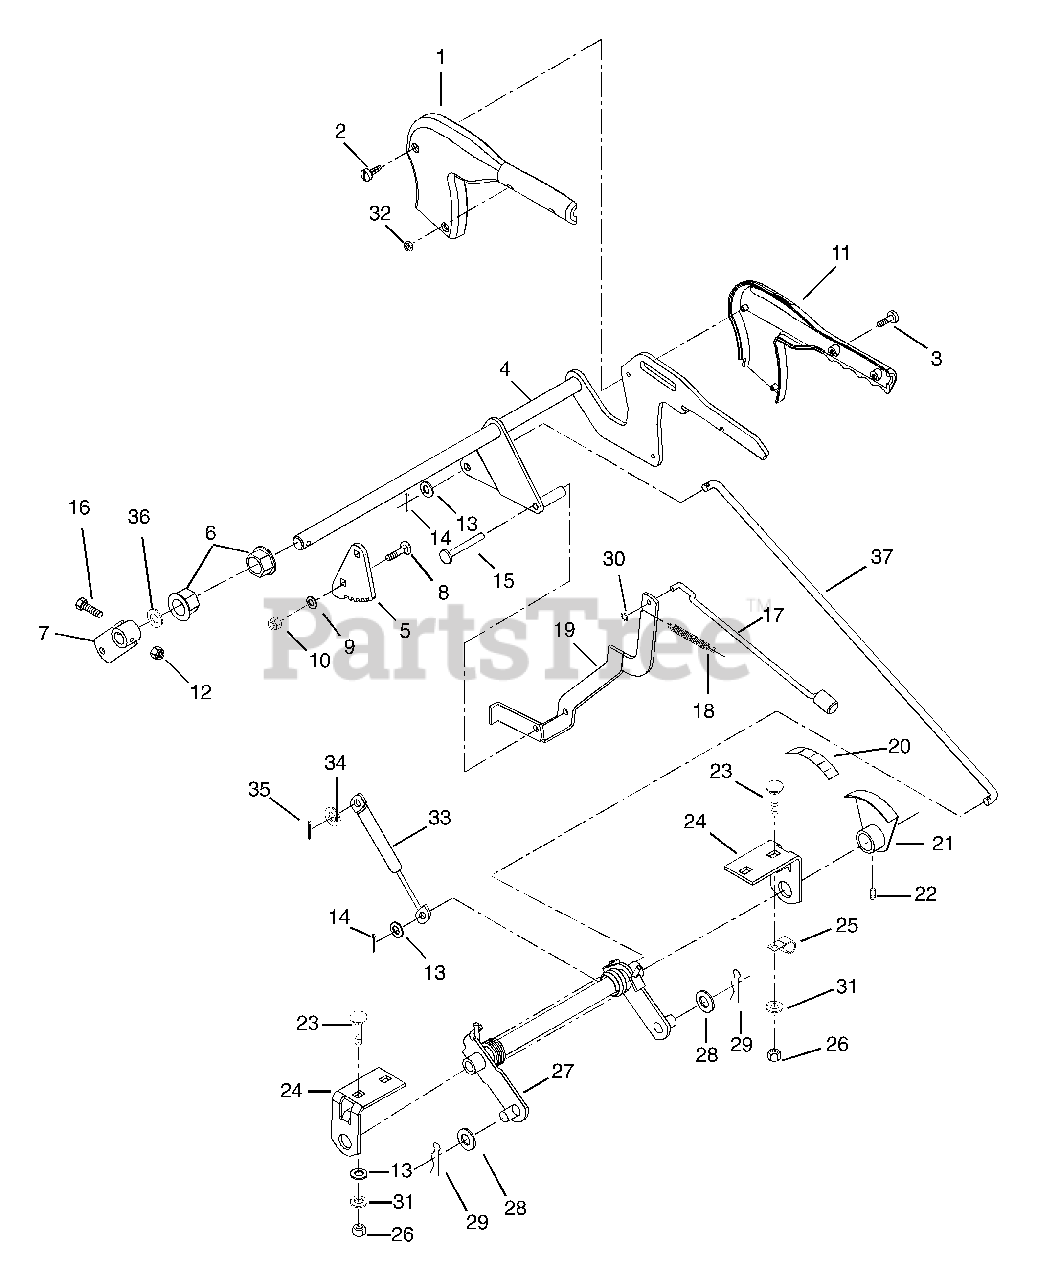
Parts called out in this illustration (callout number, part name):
1	COVER - LIFT RH
2	SCR-TAP 10-16X1.125HI-LOTPHBL
3	SCR-MCH 10-24X.62 P/HD
4	LEVER, LIFT
5	QUADRANT, LIFT
6	BSHG-FLG .750X.873HEXX.53X1.18
7	ARM, LIFT
8	@BLT-RDHDSQNK .31-18X.75 G5YZ
9	WSHR-FL-STL .323X.625X.062 YWZ
10	@NUT-LK-CTR .31-18 YWZC
11	COVER - LIFT LH
12	@NUT-LK-CTR .25-20 YWZC
13	@WSHR-FL-STL.406X.812X.065 YWZ
14	@PIN-CTR .12X1.00 EXTPRSQCT YZ
15	PIN, PIVOT .312 X 2.56
16	@BLT-HEX .25-20X1.50 GR5 YWZC
17	PIN, LIFT
18	SG-TENS .048X.44X2.25 WLD 9
19	LEVER, DETENT
20	DECAL, INDICATOR
21	INDICATOR, DECK HEIGHT(ASSY.)
22	SCR-SET .25-20X.25 SKHCUP OH
23	BLT-RHHDSQSHNK .38-16X.75 G2YZ
24	BRACKET, CENTER LIFT
25	J-CLAMP
26	@NUT-HEX .38-16 YWZC
27	LEVER, CENTER LIFT
28	WSHR-FL-STL .630X1.005X.062 YZ
29	PIN-HAIR-EXT .12X.31X2.37 YWZC
30	RG-RTNG-EXT .250X.010
31	@WSHR-LK .38X.094 REG YWZC
32	NUT,10-24 LOW CROWN, ACORN
33	SG-GAS COMP .315X.75X10.00 120
34	@WSHR-FL-STL.38X.875X.083 YWZC
35	@PIN-CTR .12X.75 EXTPRSQCT YWZ
36	@WSHR-FL-STL.812X1.50X.135YWZC
37	LIFT LINK
